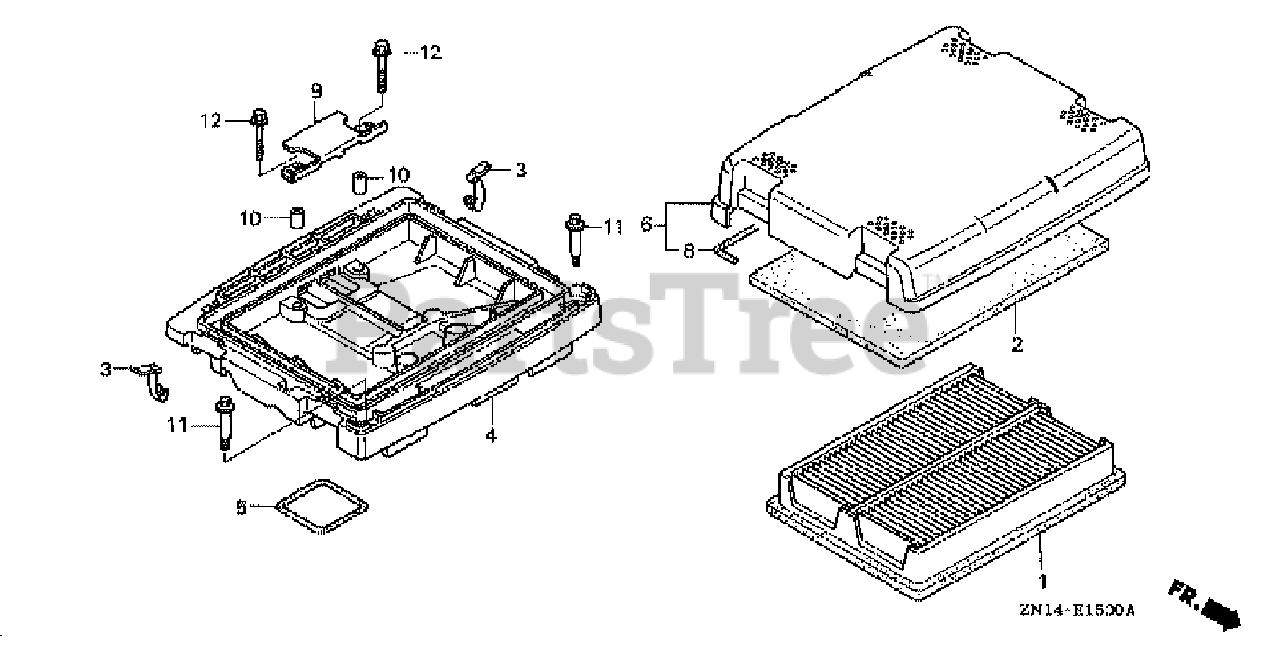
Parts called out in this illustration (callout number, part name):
1	ELEMENT, AIR CLEANER
2	FILTER (OUTER)
3	CLIP, AIR CLEANER
4	HOUSING, AIR CLEANER
5	SEAL, AIR CLEANER HOUSING
6	COVER ASSY., AIR CLEANER
8	SEAL, AIR CLEANER COVER
9	PLATE, AIR CLEANER SETTING
10	COLLAR A, AIR CLEANER
11	BOLT, SPECIAL (5MM)
12	BOLT, FLANGE (6X28)
